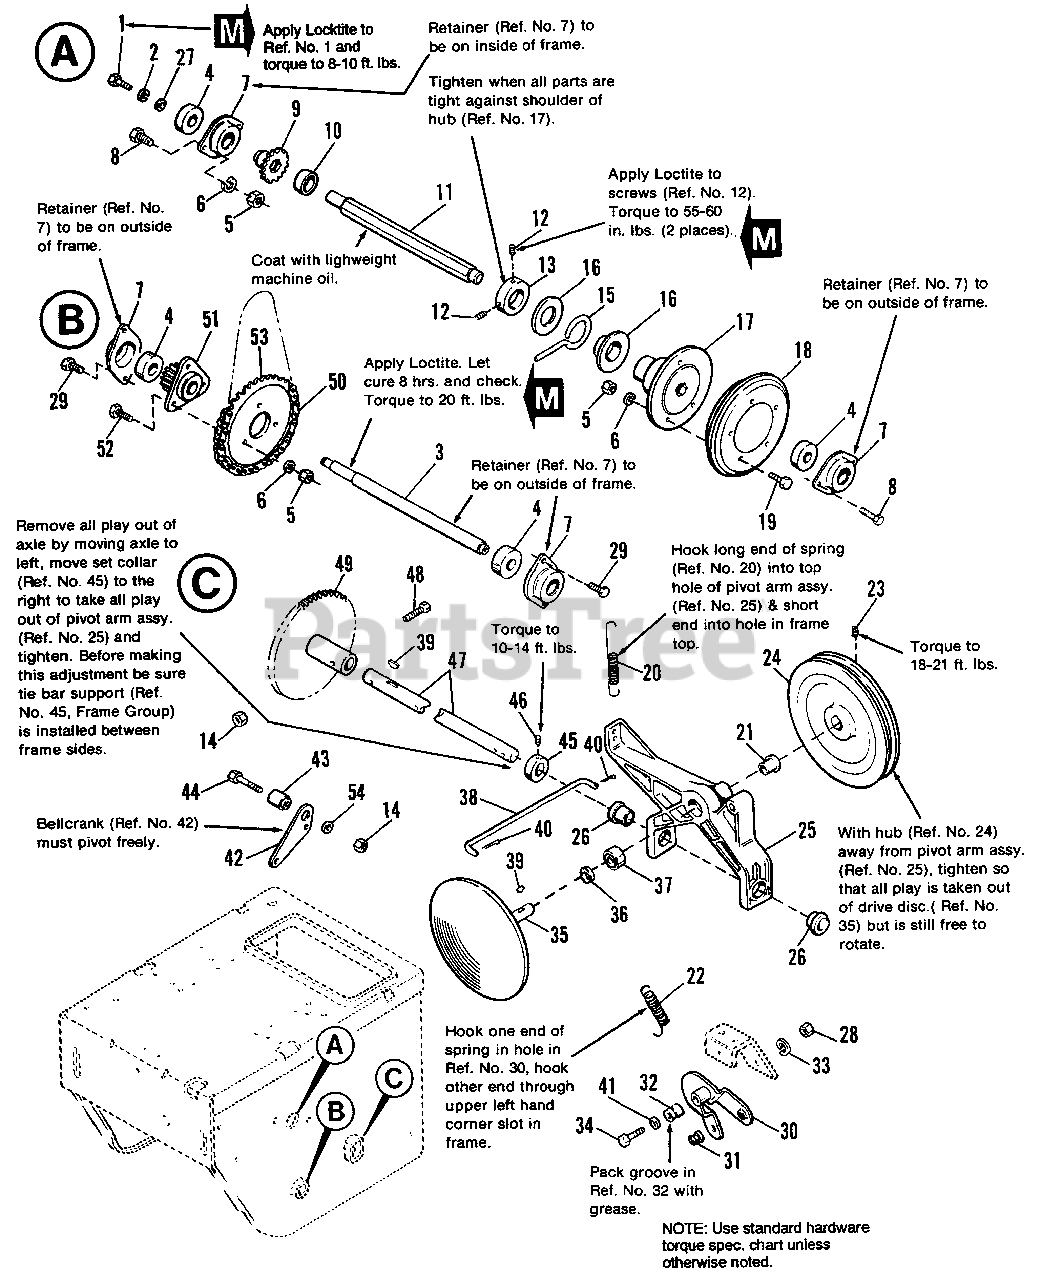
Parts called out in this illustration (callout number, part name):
1	CAPSCREW, Hex Hd., 1/4-20 x 5/8
2	LOCKWASHER, 1/4
5	NUT, Hex, 5/16-18
6	LOCKWASHER, 5/16
7	RETAINER, Bearing
8	CAPSCREW, Hex Hd., 5/16-18 x 5/8
9	SPROCKET, 10 Tooth
12	SETSCREW, Socket Hd., 1/4-20 x 3/8
14	NUT, Hex, Lock, 5/16-18
16	COLLAR, Thrust
17	HUB, Friction Disc
18	DISC, Friction
19	CAPSCREW, Hex Hd., 5/16-18 x 3/4
20	SPRING (1691000, 1691778)
20	SPRING (1691900, 1691946)
22	SPRING
23	SETSCREW, Sq. Hd., 5/16-18 x 1/2
24	PULLEY, Traction
25	ARM ASSY., Pivot w/Bushings (Incl. Ref. Nos. 21, 26 & 37)
27	WASHER, Flat, 1/4
28	NUT, Hex, 3/8-16
29	TAPTITE, 5/16-18 x 1/2
30	ARM ASSY., Shift w/Bushings (Includes Ref. No. 31)
31	BUSHING, Ball
32	BUSHING, Spacer
33	LOCKWASHER, 3/8
34	CAPSCREW, Hex Hd., 3/8-16 x 2
35	DISC, Drive
39	KEY, Woodruff, 3/16 x 5/8
40	PIN, Cotter, 1/8 x 3/4
41	WASHER, Flat, 13/32
43	BUSHING, Pivot
44	CAPSCREW, Hex Hd., 5/16-18 x 1-3/4
45	SET COLLAR
46	SETSCREW, Sq. Hd., 5/16-18 x 1/2
48	CAPSCREW, Hex Hd., 5/16-18 x 1-1/2
50	CHAIN, Drive
51	GEAR AND BEARING ASSY., 10 Tooth (1691777, 1691778)
51	GEAR AND BEARING ASSY., 10 Tooth (1691990, 1691946)
52	CAPSCREW, Hex Hd., 5/16-18 x 1
53	SPROCKET, 36 Tooth
54	WASHER, Flat, 11/32
